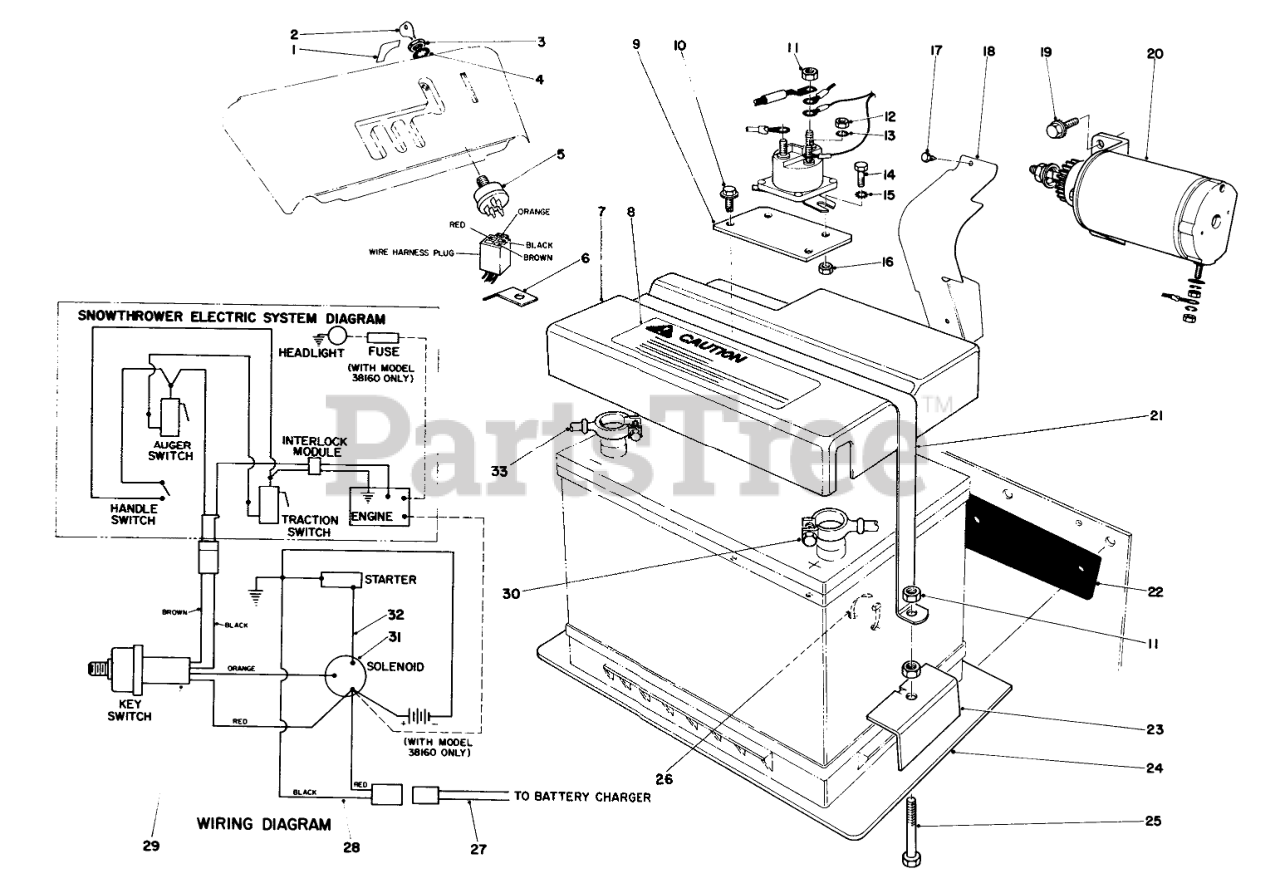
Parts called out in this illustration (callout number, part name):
1	Decal Switch
2	Key
3	NUT-HH
4	WASHER-TOOTH, INTERNAL
5	Starter Switch (Incl.Ref. #3&4)
6	Bracken Wire Clamp
7	Battery Cover (Incl.Ref. #8)
8	Decal-Caution
9	Bracket Solenoid
10	SCREW-HWH
11	NUT-HEX
12	NUT-HEX
13	WASHER-LOCK, INT
14	SCREW-HH
15	WASHER-LOCK/EXT
16	NUT-LOCK, NI
17	Hex Hd. Sems Screw
18	Pinion Shield
19	Screw-HH
20	Starter Motor & Pinion Assy.
21	Strap Battery
22	Batery Isolation Pad
23	BATTERY CLAMP
24	Battery Mounting Plate
25	SCREW-HH
26	TIE-CABLE
27	MALE WIRE ASM
28	FEMALE WIRE ASM
29	Wire Harness
30	BATT-SOLENOID CABLE
31	SOLENOID
32	STRT MTR-SOLNOID WIRE
33	BATT-GROUND CABLE
